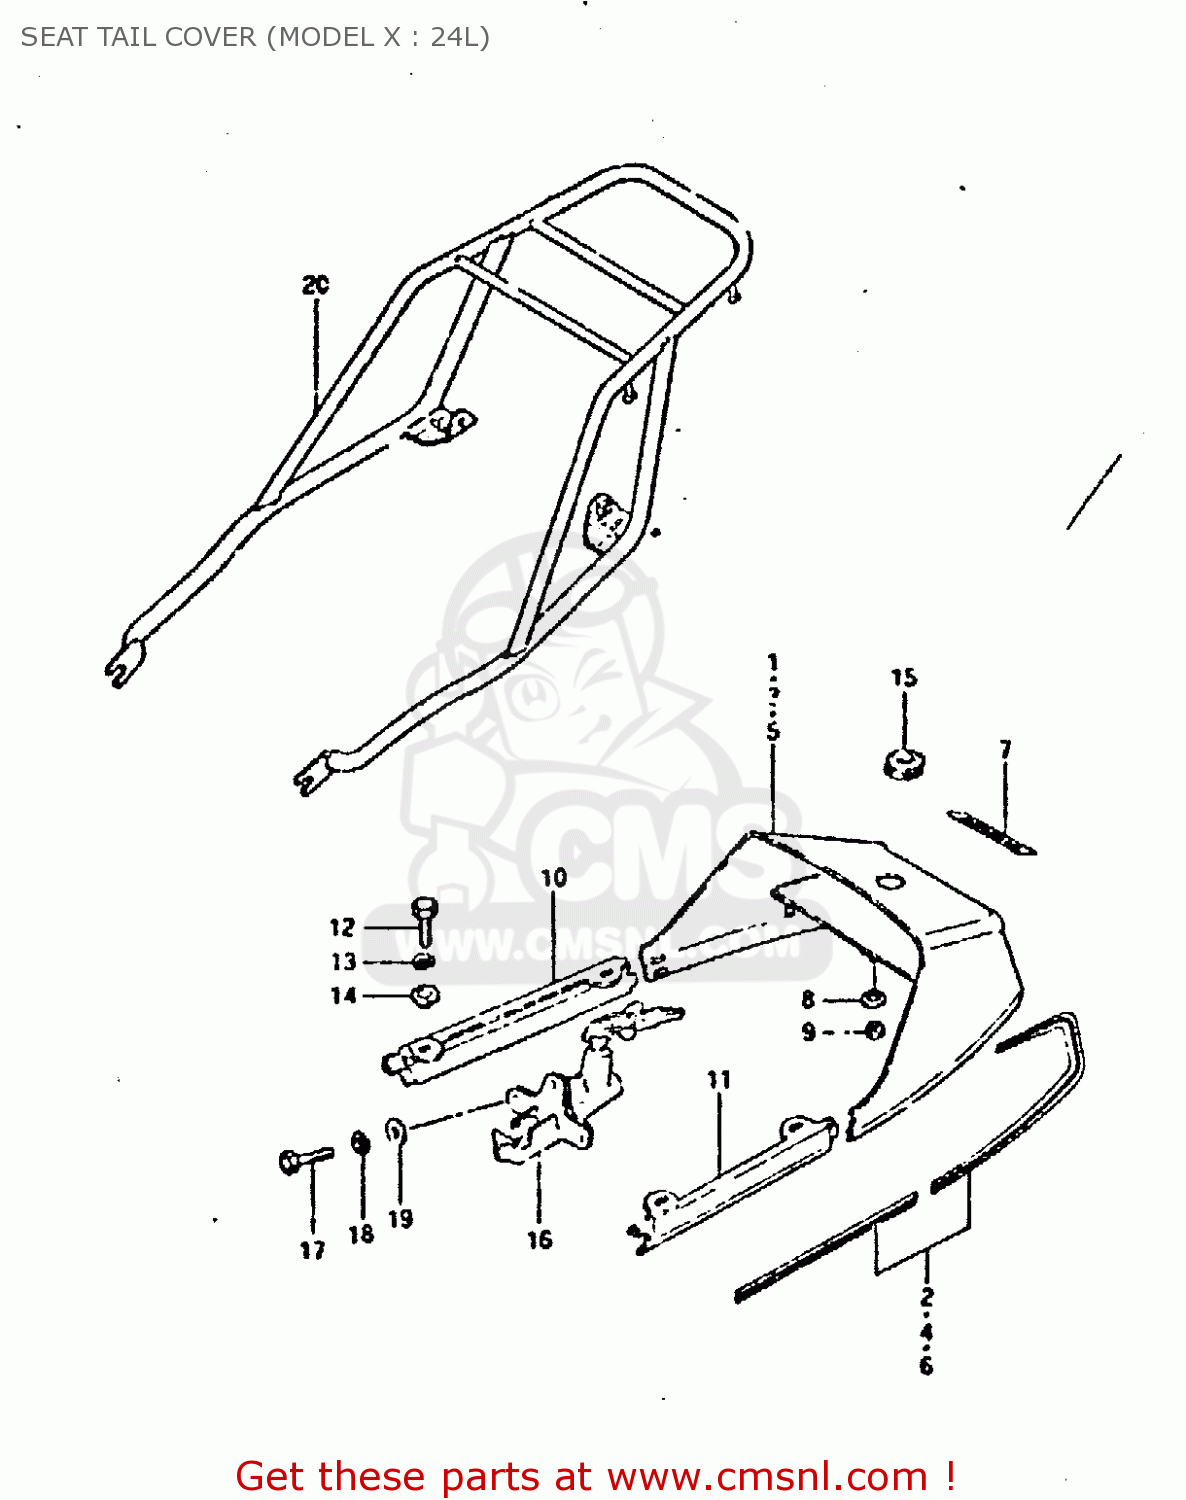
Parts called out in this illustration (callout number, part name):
1	COVER SET, SEAT TAIL (BLACK)
2	TAPE SET
3	COVER SET, SEAT TAIL (RED)
4	TAPE SET
5	COVER SET, SEAT TAIL (BLUE)
6	TAPE SET
7	EMBLEM (GOLD/BLACK)
8	WASHER
9	NUT 6MM
10	MOULDING, SEAT RH (RED)
11	MOULDING, SEAT LH (RED)
12	BOLT
13	LOCK WASHER
14	WASHER
15	GROMMET,SEAT LOCK HOLE
16	LOCK SET,SEAT
17	BOLT
18	LOCK WASHER
19	WASHER 6MM
20	CARRIER
